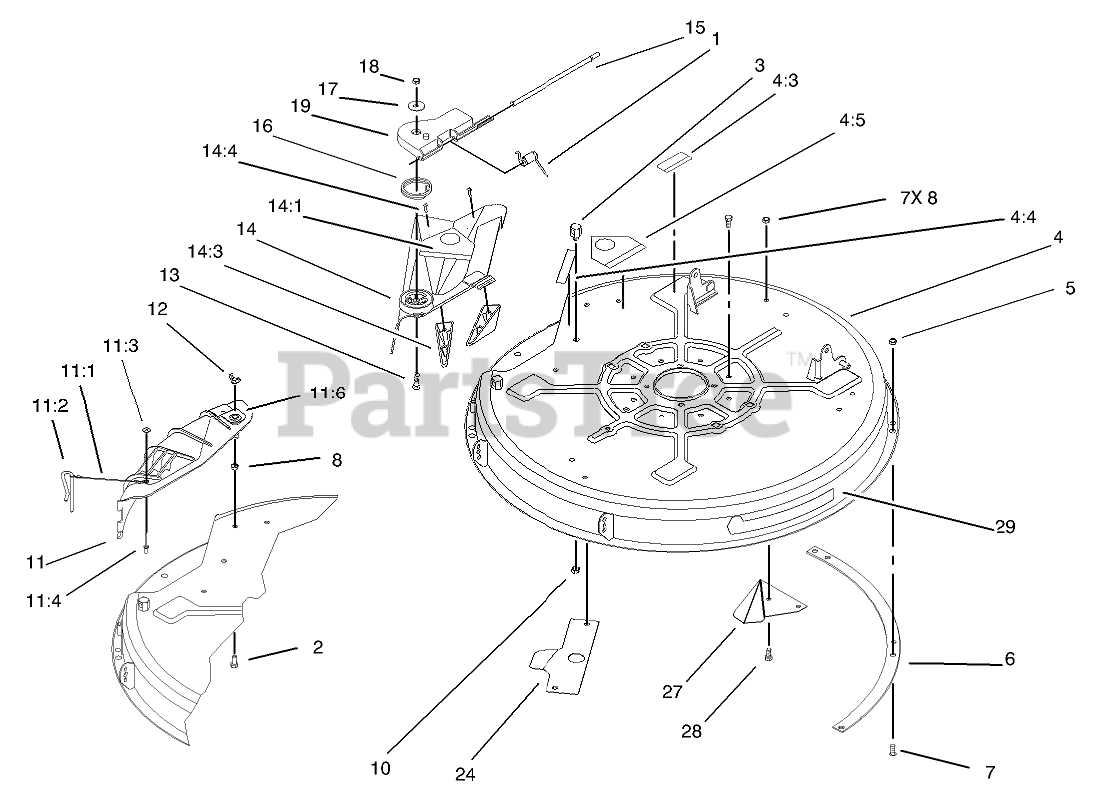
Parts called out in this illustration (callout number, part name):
1	SPRING-TORSION
2	SCREW-HH
3	POST-PIVOT
4	DECK ASM
4:3	DECAL-WARNING
4:4	DECAL-DANGER
4:5	DECAL-DANGER
5	NUT-LOCK, NI
6	RING-DECK
7	SCREW-HH
8	NUT-LOCK, NI
10	NUT-LOCK, NI
11	DISCHARGE COVER ASM
11:1	LANYARD
11:2	PIN-LOCKING, CHUTE
11:3	WASHER-PLAIN
11:4	RIVET-BLIND
12	NUT-WING
13	BOLT-SHOULDER
14	32 INCH DEFLECTOR ASM
14:1	DECAL-DANGER
14:3	KICKER
14:4	SCREW-PPH
15	ROD-HINGE, DEFLECTOR
16	SPRING-TORSION
17	WASHER-FLAT
18	NUT-LOCK, NI
19	PIVOT-HINGE, DEFLECTOR
24	RAMP-DEFLECTOR
28	SCREW-HH
29	DECAL-RECYCLER
